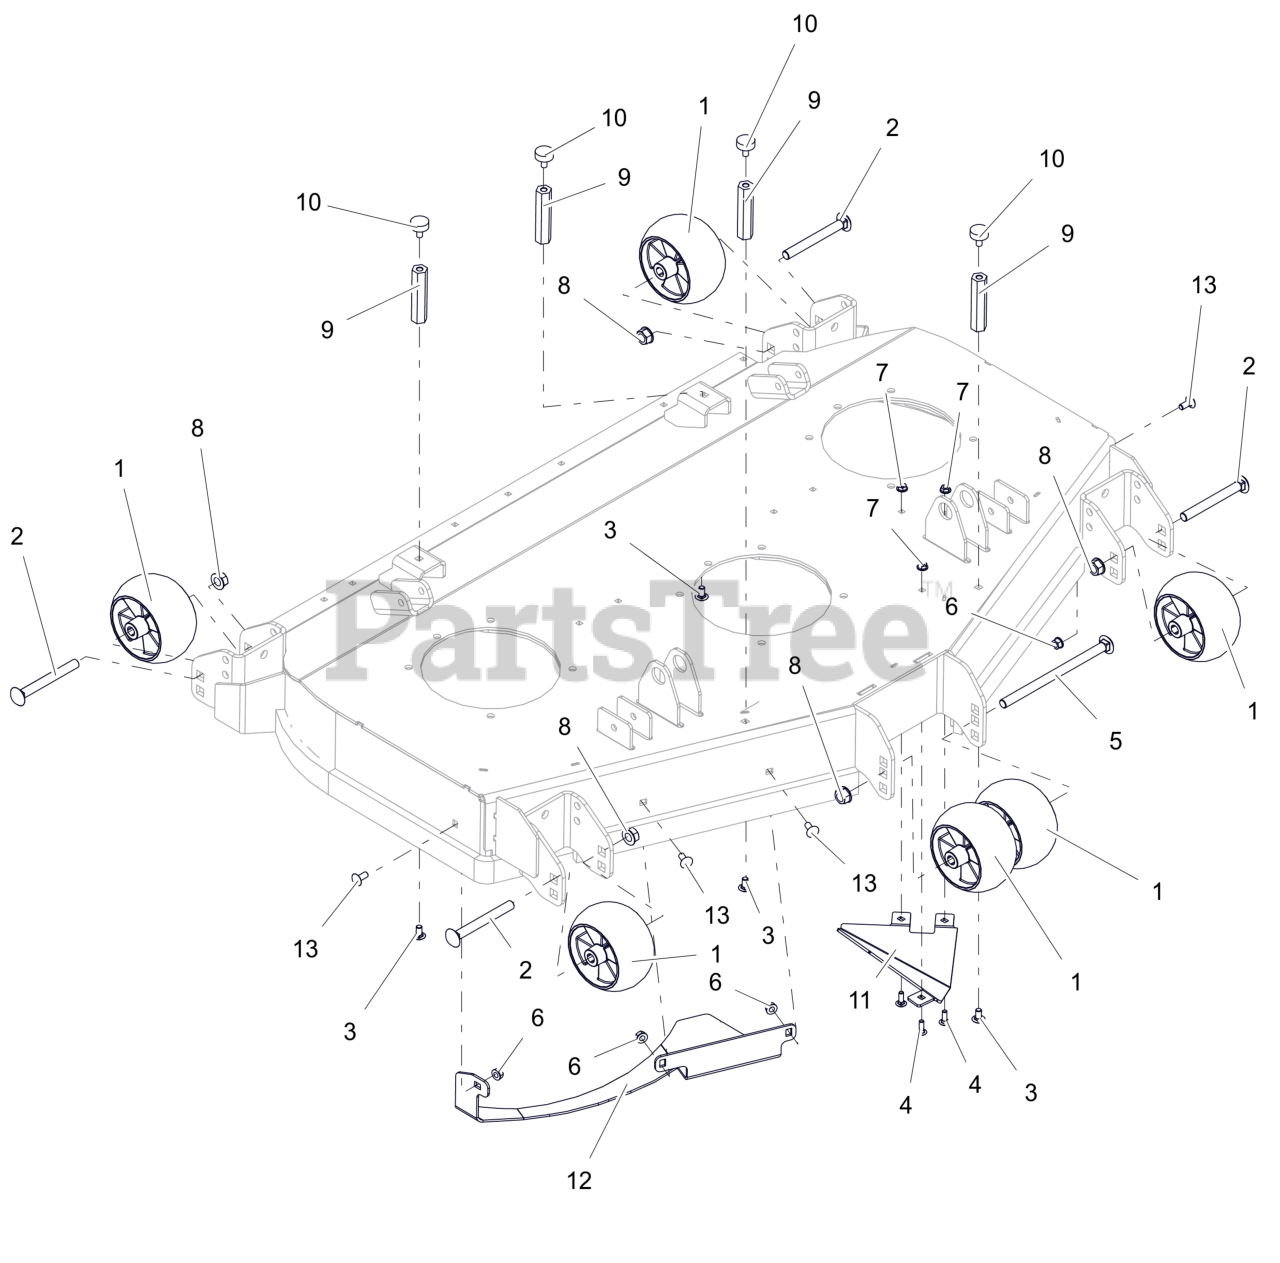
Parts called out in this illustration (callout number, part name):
1	WHEEL, ANTI SCALP - 5X3 CTR W/RIBS
2	BLT,RHSN .50-13X4.50 G5 ZCC
3	BLT,RHSSN.31-18X.625 G5 ZCCP30
4	BLT, RHSN .25-20X.750 G5 ZCC
5	BTL,RHSN .500-13 X 8 G5 ZCC
6	NUT,LK-CTR-FLG .31-18 GF ZCC
7	NUT-LK-CTR-FLG .25-20 ZC120
8	NUT-LK-CTR-FLG .500-13 GG ZCC
9	NUT, COUPLING .312-18 X 3.375
10	BUMPER, RUBBER
11	BAFFLE, 48" TRIANGLULAR INSERT (ORANGE)
12	DEFLECTOR, BAFFLE BOLT-IN (ORANGE)
13	BLT, RHSSN.31-18X.750 G5 ZCC
